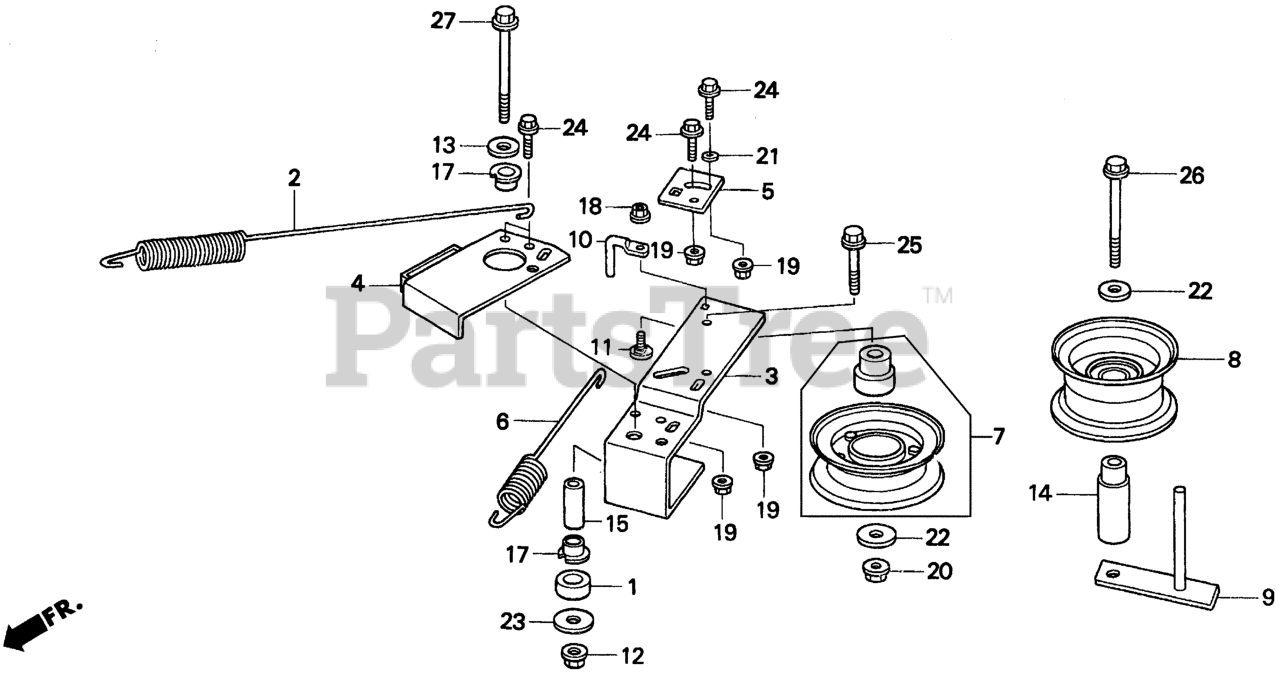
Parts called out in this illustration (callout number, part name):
1	COLLAR, MAIN PIPE ENGINE HANGER (A)
2	SPRING, TENSIONER ARM
3	ARM, TENSIONER
4	ARM, BRAKE
5	PLATE, ADJUSTING
6	SPRING B, TENSION
7	ROLLER, TENSION
8	PULLEY, IDLER
9	STOPPER B, BELT
10	STOPPER D, BELT
11	BOLT, SPECIAL (8X20)
12	NUT, SELF-LOCK (10MM)
13	WASHER, PLAIN (10.3MM)
14	COLLAR, IDLE ROLLER
15	COLLAR, TENSION
17	COLLAR C, TENSIONER
18	NUT, HEX. (8MM)
19	NUT, FLANGE (6MM)
20	NUT, FLANGE (8MM)
21	WASHER, PLAIN (6MM)
22	WASHER, PLAIN (8MM)
23	WASHER, PLAIN (10MM)
24	BOLT, FLANGE (6X20)
25	BOLT, FLANGE (8X40)
26	BOLT, FLANGE (8X70)
27	BOLT, FLANGE (10X85)
